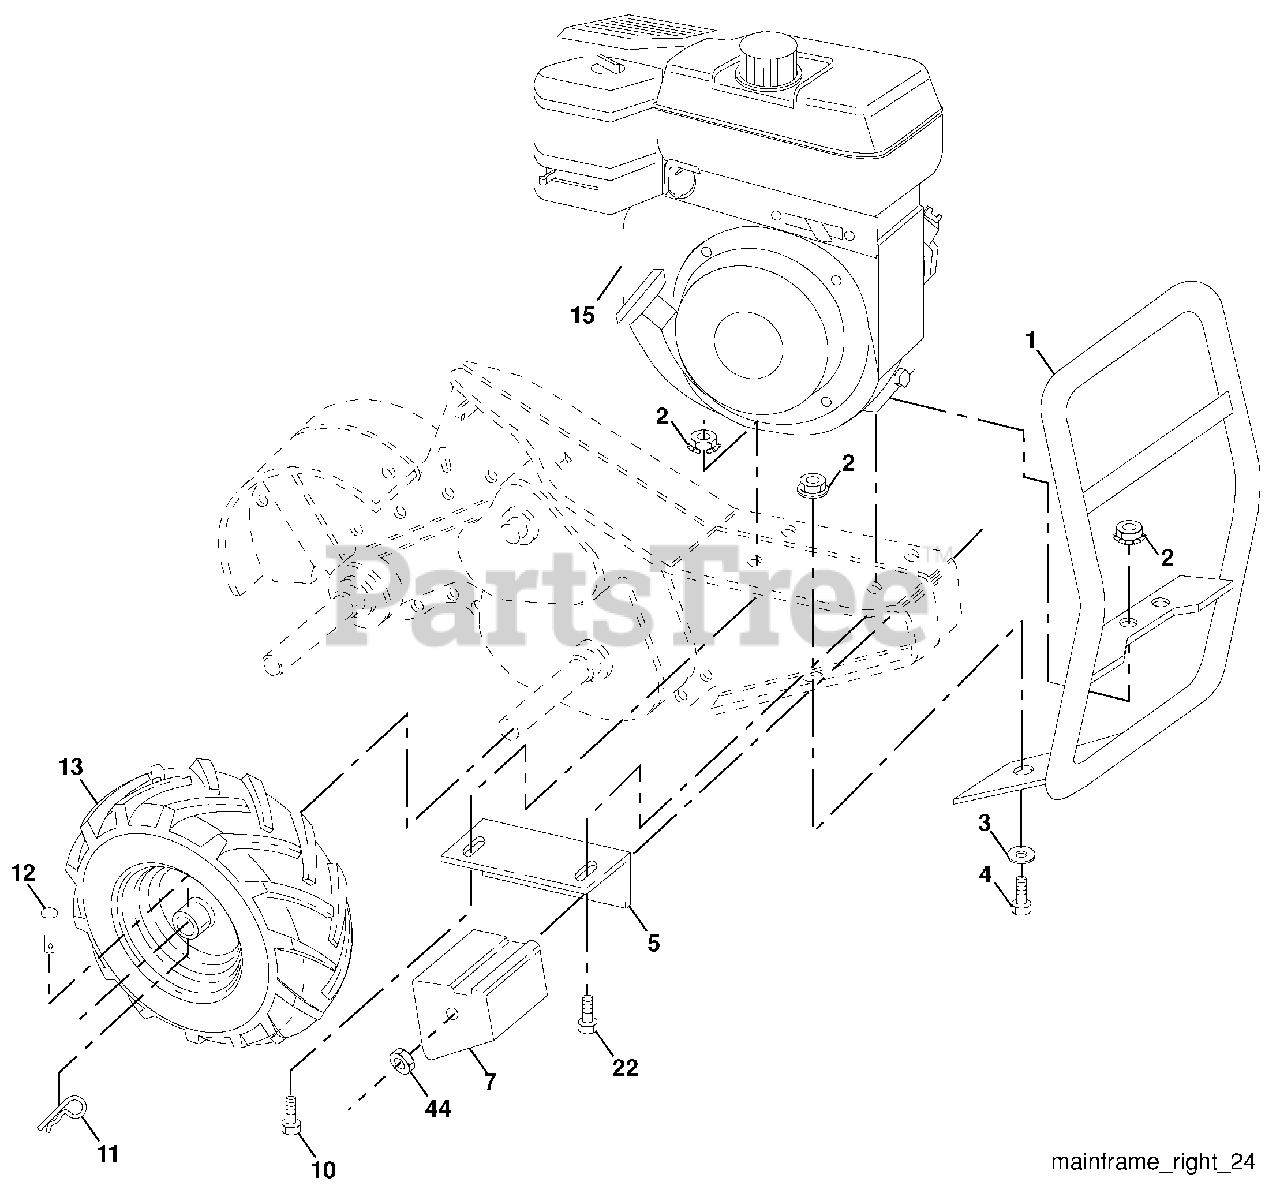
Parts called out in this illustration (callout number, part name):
2	Locknut, Hex, Flange 5/16-18
3	Washer 11/32 x 11/16 x 16 Ga.
4	Bolt, Hex 5/16-18 x 3/4
5	Bracket, Reinforcement
7	Counter Weight, R.H.
10	Bolt, Hex 5/16-18 x 1-1/2
11	Clip, Hairpin
12	Rivet, Drilled
13	Tire
13	Rim
13	Tire Valve
22	Bolt, Hex 5/16-18 x 1-3/4
44	Nut, Keps, Hex 3/8-16 unc
